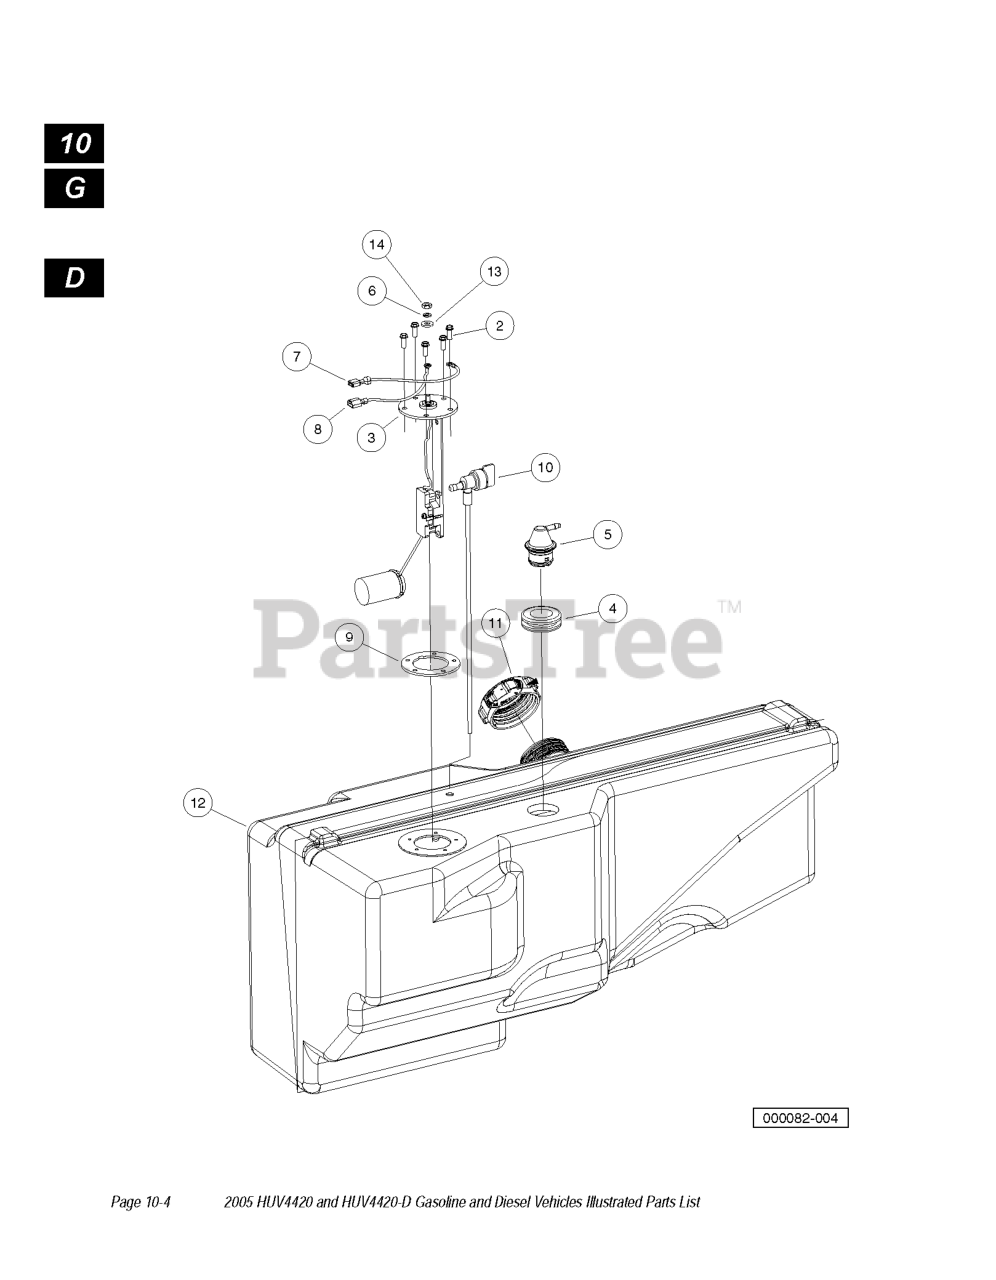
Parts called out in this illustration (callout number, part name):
1	ASM, TANK, GASOLINE, SIDEFILL
2	SCREW
3	FUEL GUAGE SENDING UNIT
4	INSULATION GROMMET
5	FUEL TANK VENT ASSY
6	WASHER,#10 SPLIT WASH
9	GASKET, SEND UNIT (RUBBER)
10	VALVE, PICKUP TUBE, FUEL
11	CAP, FUEL TANK - GASOLINE
13	WASHER FLAT
14	NUT, #10-32 BRASS HEX
